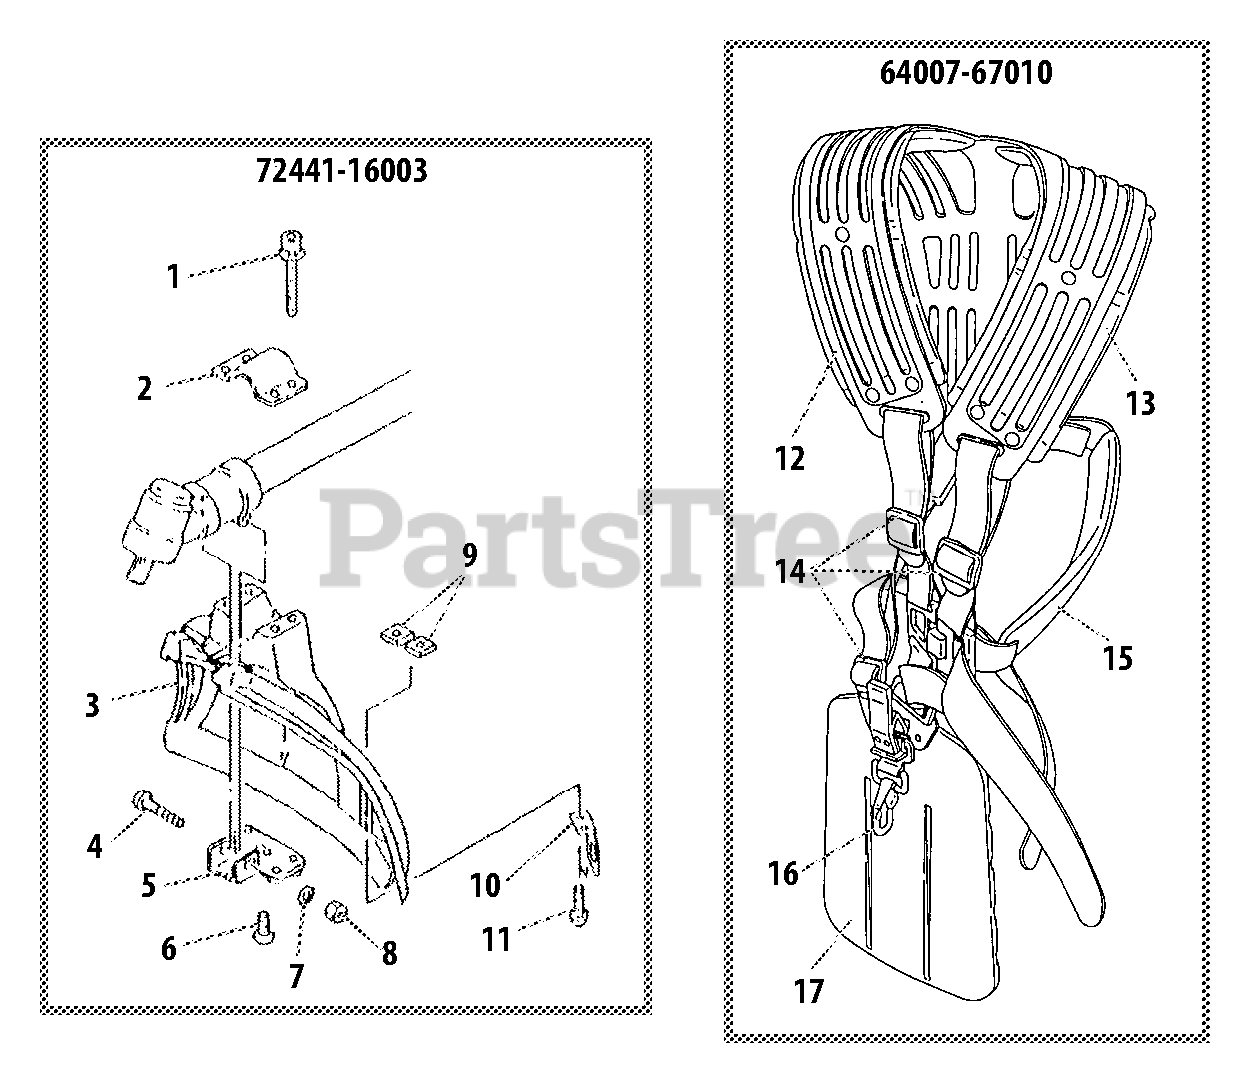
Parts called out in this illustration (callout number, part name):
1	BOLT M5×45
2	CLAMP, UPPER
3	SHIELD, DEBRIS
4	BOLT M6×40
5	CLAMP, LOWER
6	SCREW HILO 4×10
7	WASHER 6.5×13×1
8	NUT, HEX M6
9	NUT M5
10	CUTTER
11	BOLT M5×16
12	PAD - RIGHT
13	PAD - LEFT
14	BUCKLE
15	PAD, SHOULDER
16	HOOK
17	PAD
64007-67010	HARNESS ASSY
72441-16003	DEBRIS SHIELD ASSY
